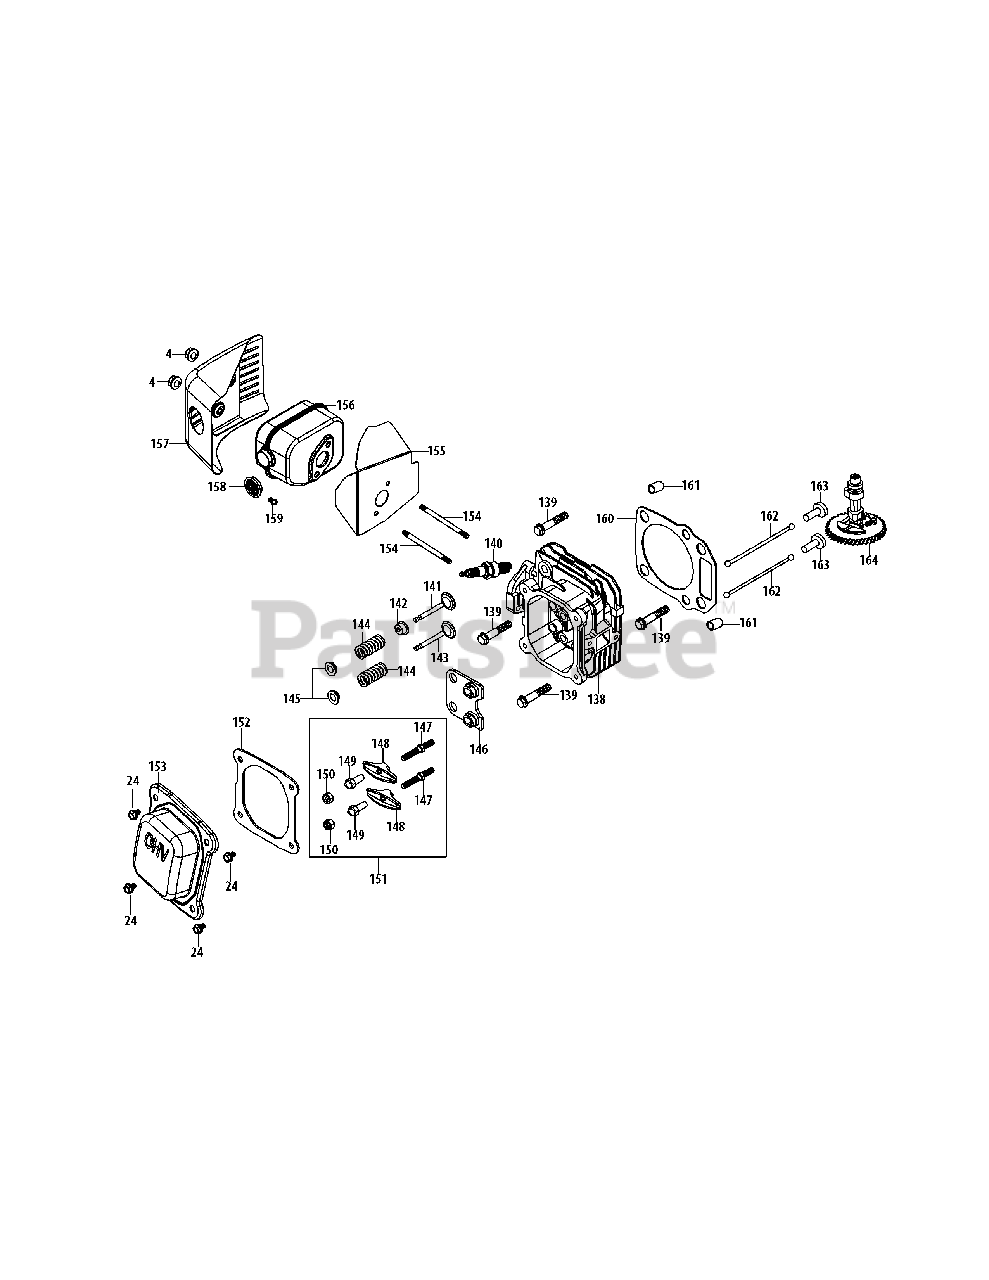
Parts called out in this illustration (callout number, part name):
4	Nut M6X10M
24	Bolt M6X14
138	Cylinder Head Assembly
139	Bolt M8X54 Cylinder Head
140	Spark Plug/F6Rtc
142	Intake Valve Seal
144	Valve Spring
145	Valve Spring Retainer
146	Push Rod Guide
147	Rocker Arm Stud
148	Rocker Arm
149	Fulcrum Nut
151	Rocker Arm Assembly
152	Valve Cover Gasket
153	Valve Cover
154	Muffler Stud M6X95
154	Muffler Stud Assemlby
155	Muffler Gasket
156	Muffler Assembly
157	Muffler Shield
158	Spark Arrestor
159	Spark Arrestor Screw
160	Cylinder Head Gasket
161	Cylinder Head Dowel Pin 10×16
162	Push Rod Kit
164	Camshaft Assembly
